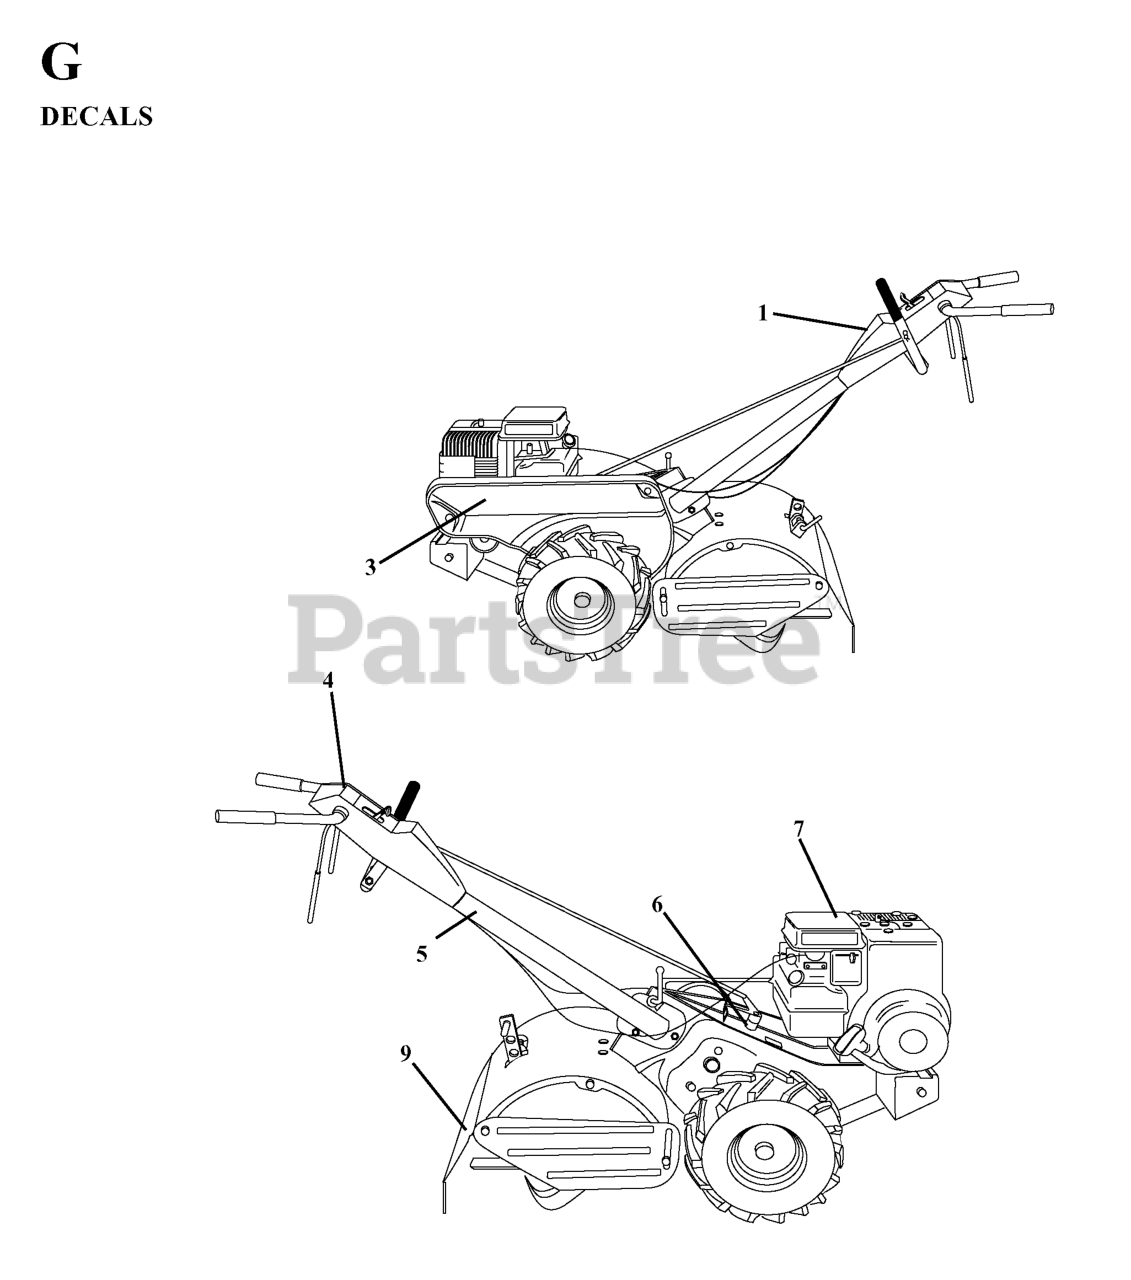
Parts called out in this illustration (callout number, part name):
1	DECAL, LOGO
4	DECAL, LOGO
5	DECAL TI (2 2)
6	DECAL TI NLA
